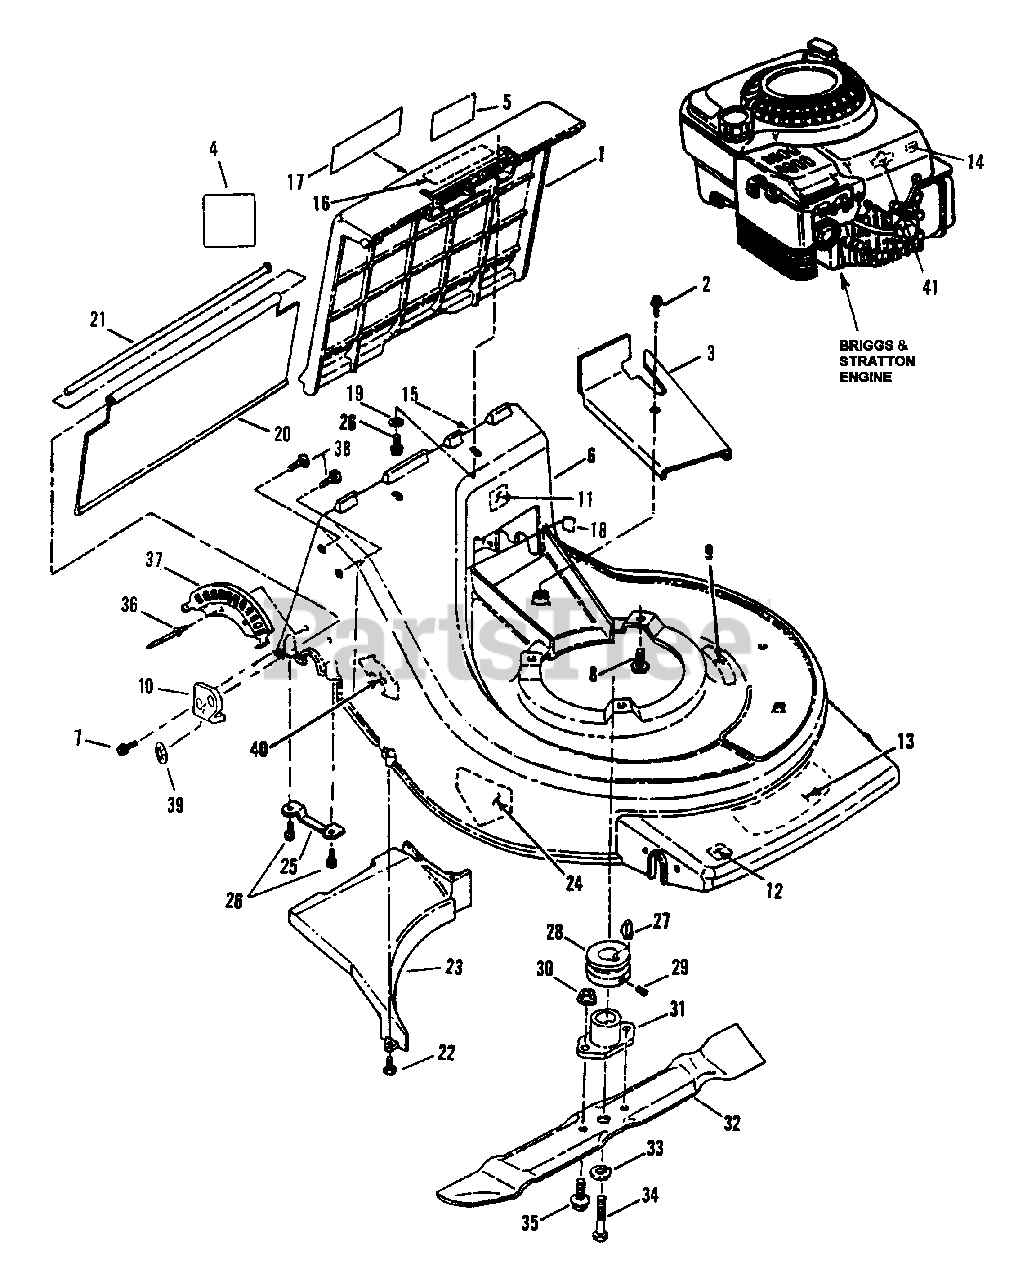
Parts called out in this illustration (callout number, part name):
1	ASSEMBLY, Discharge Door
2	SCREW, #10-24 x 1-1/2" Slotted, Hex Washer Head, Self-Tapping
3	COVER, Belt/Tie Bar
4	DECAL, Year of Manufacture
5	DECAL, WARNING
6	DECK, 21" Cast Aluminum
7	SCREW, 1/4-20 x 5/8" Hex Washer Head Self-Tapping
8	SCREW, 3/8-16 x 1" Hex Head, Self-Tapping
9	DECAL, WARNING (Deck)
10	BRACKET, RH Pivot Rod
11	DECAL, Noise Control
12	DECAL, European Community
13	LOGO, SNAPPER Cast Aluminum Series
14	DECAL, Spark Plug
15	DECAL, Deck/Chute, International Warning
16	DECAL, WARNING Chute Deflector
17	DECAL, Convertible Mower
18	DECAL, Patent Numbers
19	WASHER, 1/4" Flat
20	SHIELD, Trailing
21	ROD, Trailing Shield Pivot
22	SCREW, #10-24 x 5/8" Slotted, Hex Washer Head, Self-Tapping
23	BAFFLE, Discharge
24	DECAL - DANGER
25	SUPPORT, Rear Axle
26	SCREW, 1/4-20 x 5/8" Hex Washer Head, Self-Tapping
27	KEY, HP-506 Hi-Pro
28	PULLEY, Traction Drive
29	SCREW, 5/16-18 x 5/16" Hex. Socket Set
30	NUT, 3/8-16 Hex Nyloc
31	HUB, 25 mm Blade Drive
32	BLADE, 21" Mulching/Bagging
33	WASHER, 3/8 Split Lock (Heavy)
34	SCREW, 3/8-24 x 1-3/4" Hex Head Cap, Grade 5
35	BOLT, 3/8-16 x 1-1/4" Hex Flange Lock
36	RIVET, 3/16 x 1/2" Steel
37	PLATE, Height Adjustment
38	BOLT, 5/16-18 x 1" Carriage, Gr. 5
39	PUSH-NUT, 1/4"
40	DECAL, Height Adjustment
41	LOGO, Briggs & Stratton
